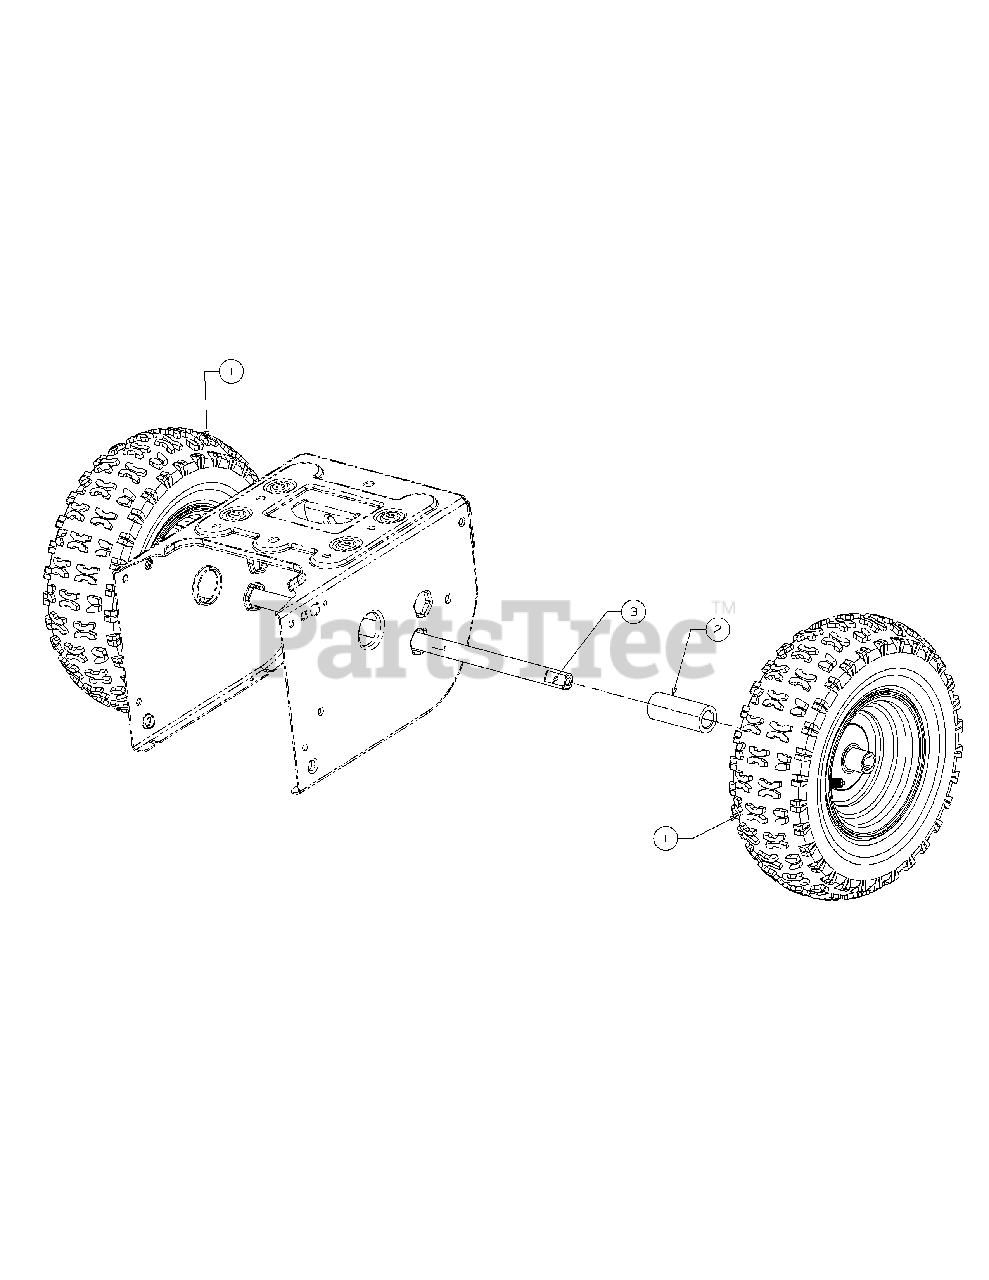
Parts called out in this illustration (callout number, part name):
1	Wheel Asm-Comp
2	Spacer-Wheel 1.25O
3	Shaft-Wheel Axle
